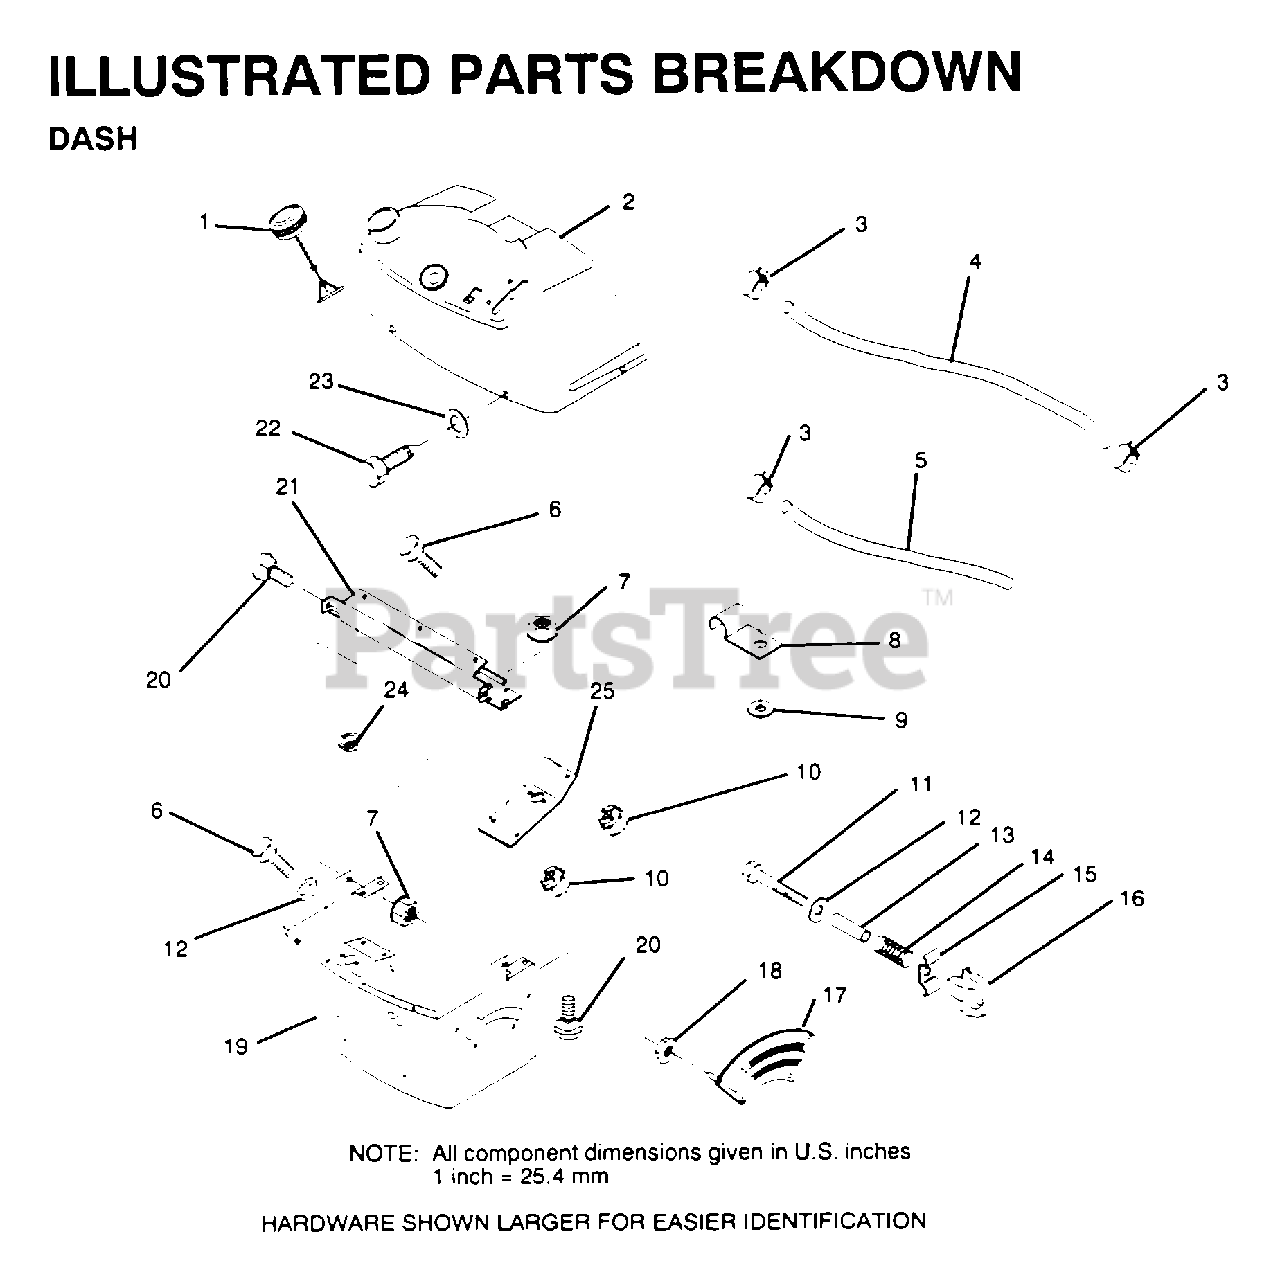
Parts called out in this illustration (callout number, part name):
3	HOSE CLAMP
4	FUEL LINE T
7	NUT
8	CLIP T
9	WASHER PM
10	LOCKNUT
11	BOLT
12	WASHER
13	SPACER SPLIT
14	SPRING T
15	HEIGHT ADJ
16	KNOB
17	ADJUSTER QUAD
18	NUT
19	SUPPORT DASH
20	BOLT
21	"BRAKE,CROSS"
25	"PLATE,SUPT "
